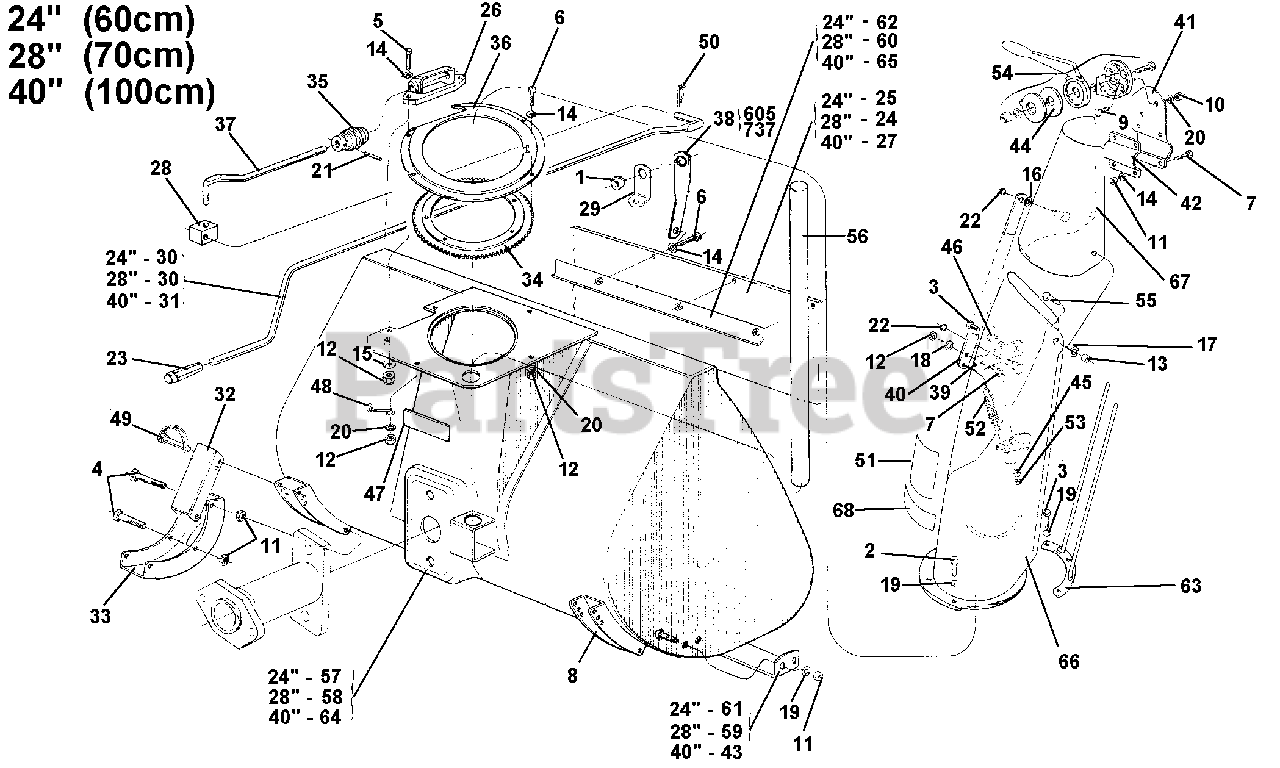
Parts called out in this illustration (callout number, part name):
2	SCREW TE M6 X 10 UNI 5739-5S
3	SCREW TE M6 X 14
4	SCREW TE M6 X 55
5	SCREW M6 X 25
6	SCREW TE M6 X 16
7	SCREW M6 X 20
8	SCREW M6 X 16
9	SCREW TSV M6 X 16 UNI 260-5S
11	NUT, SELF LOCKING M6
12	SELF LOCKING NUT M6
13	NUT, SELF LOCKING M10
14	WASHER, FLAT 6.4
15	FLAT WASHER
17	FLAT WASHER 10.5 X 21
18	WASHER, FLAT 6.4
19	SUPER WASHER 6 DIN 6796
20	WASHER, LOCK 6.4
21	PIN, LOCKING SW 3 X 22 SPIRAL
22	RETAINING RING
24	MUDFLAP 70 CM
25	MUDFLAP 60 CM
26	SCREW SUPPORT
27	MUDFLAP 100 CM
30	FUNNEL CONTROL ROD
31	FUNNEL CONTROL ROD
37	ROD EXTENSION
40	FLAP TIEROD
41	LEVER SUPPORT
43	BLADE 100 CM
44	RING FOR LEVER
45	END, SHEATH
46	PIN, CABLE CLAMP
47	DECAL-CHIPPER
48	GAS SHEATH SUPPORT
51	FUNNEL STICKER
52	FUNNEL SPRING
53	ROCKER ARM WIRE AND SHEATH
54	SNOW THROWER HANDLE
55	SCREW M10 X 25
57	BLADE 70 CM
58	SNOW THROWER CRANKCASE 70 CM
59	BLADE 70 CM
60	SNOW THROWER CRANKCASE 60 CM
61	BLADE 60 CM
62	MUD FLAP STOP 60 CM
63	FUNNEL GRATE
64	SNOW THROWER CRANKCASE 100 CM
65	STOP 100 CM
66	SNOW THROWER FUNNEL
68	STICKER "MADE IN ITALY
